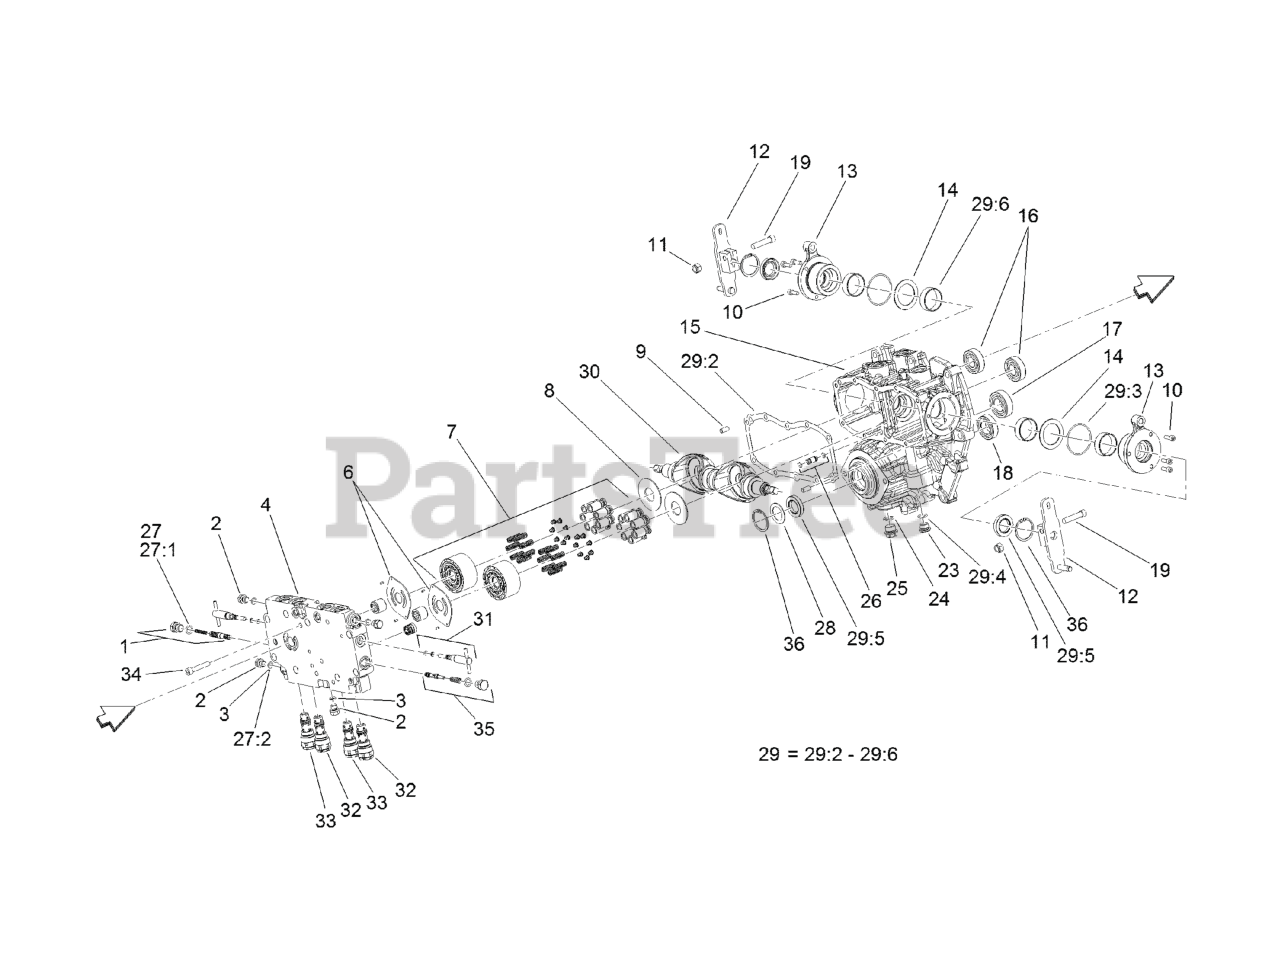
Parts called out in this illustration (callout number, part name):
1	VALVE-FLUSHING, RH
3	O RING-PLUG
4	CENTER CASE, COMPLETE
6	PLATE-VALVE
7	CYLINDER BLOCK ASM
8	PLATE-THRUST
9	PIN-PARALLEL
12	ARM-CONTROL
13	SIDE COVER ASM
15	PUMP HOUSING ASM
16	BEARING
17	BEARING
18	BEARING
23	PLUG-NPTF
24	O-RING
27	CENTER CASE SEAL KIT
27:2	O RING-PLUG
29	PUMP HOUSING SEAL KIT
29:2	GASKET-CASE, CENTER
29:3	O RING-PLUG
29:4	Packing
29:6	RING-SEAL
30	PLATE-SWASH
31	VALVE-BYPASS
32	VALVE-REAR
33	VALVE-FRONT
35	VALVE-FLUSHING, LH
36	RING-SNAP
